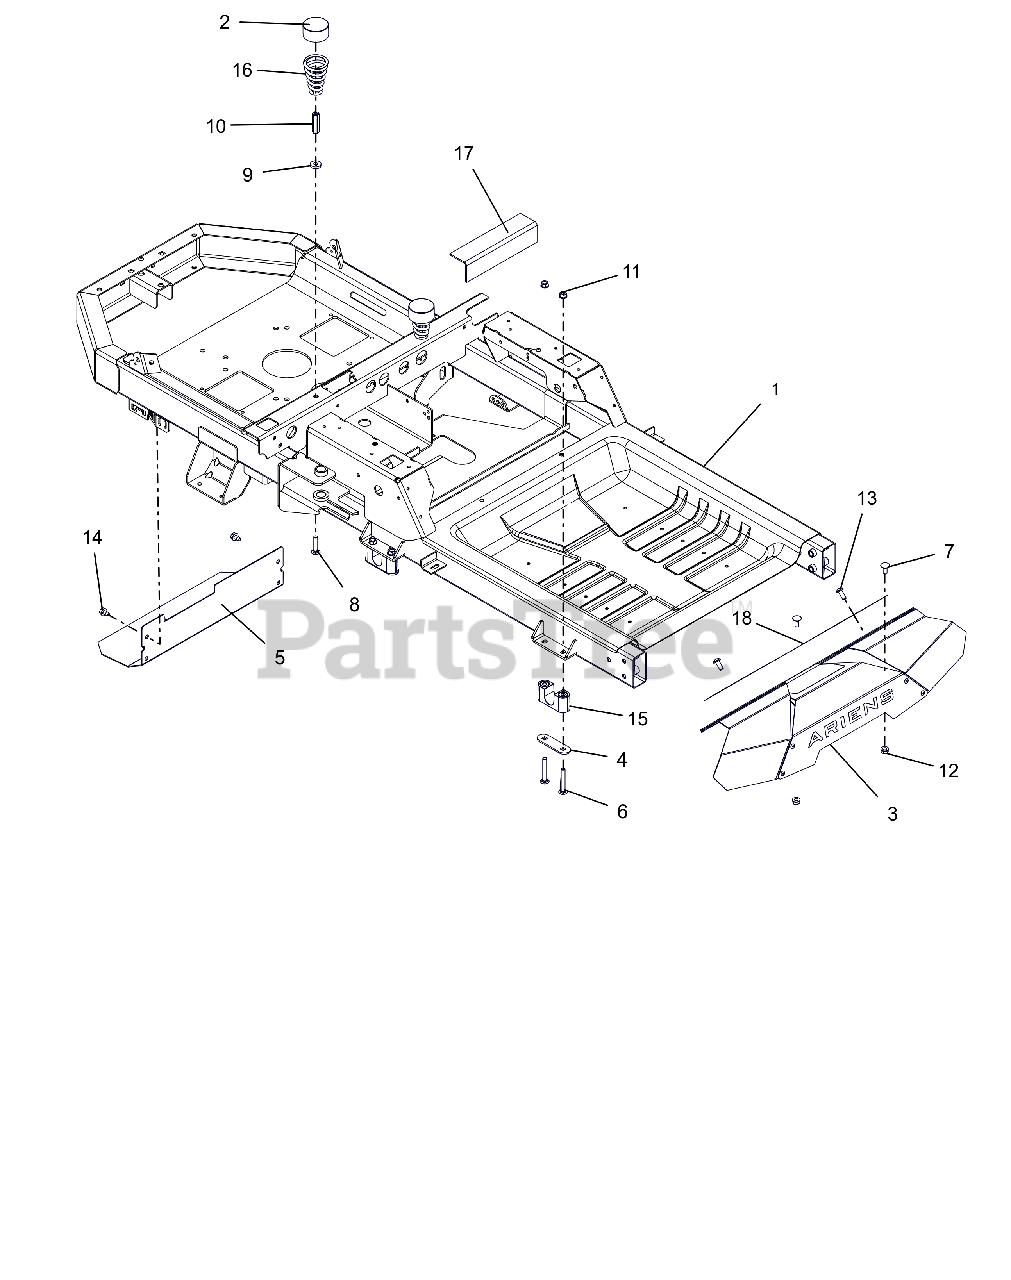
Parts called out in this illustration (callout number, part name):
1	KIT, IKON-X/XL FRAME (2016)
2	HUB CAP
3	KIT, IKON FOOT REST W/DECAL
4	PLATE, BEARING SUPPORT
5	HEAT, SHIELD
6	BLT, RHSSN.31-18X2.25 G5 ZCC
7	BLT,RHSN .31-18X.75 G5 ZCC
8	BLT,RHSN .31-18X1.50 G5 ZCC
9	WSHR, FLT .328X.870X.179 ZCC
10	NUT, COUPLING .31-18X1.75 ZCC
11	NUT,LK-CTR-FLG .31-18 GF ZCC
12	NUT-LK-TOP-FLG .312-18 GF ZCC
13	SCR-RDHDSKTAP .31-18 X .75
14	SCR,TAP .312-18X.50 HWH TR ZCC
15	BSHG, DECK LIFT PIVOT
16	SPRING, SEAT
17	PAD, RUBBER-TANK
18	GRIP TAPE, FOOT PLATE
